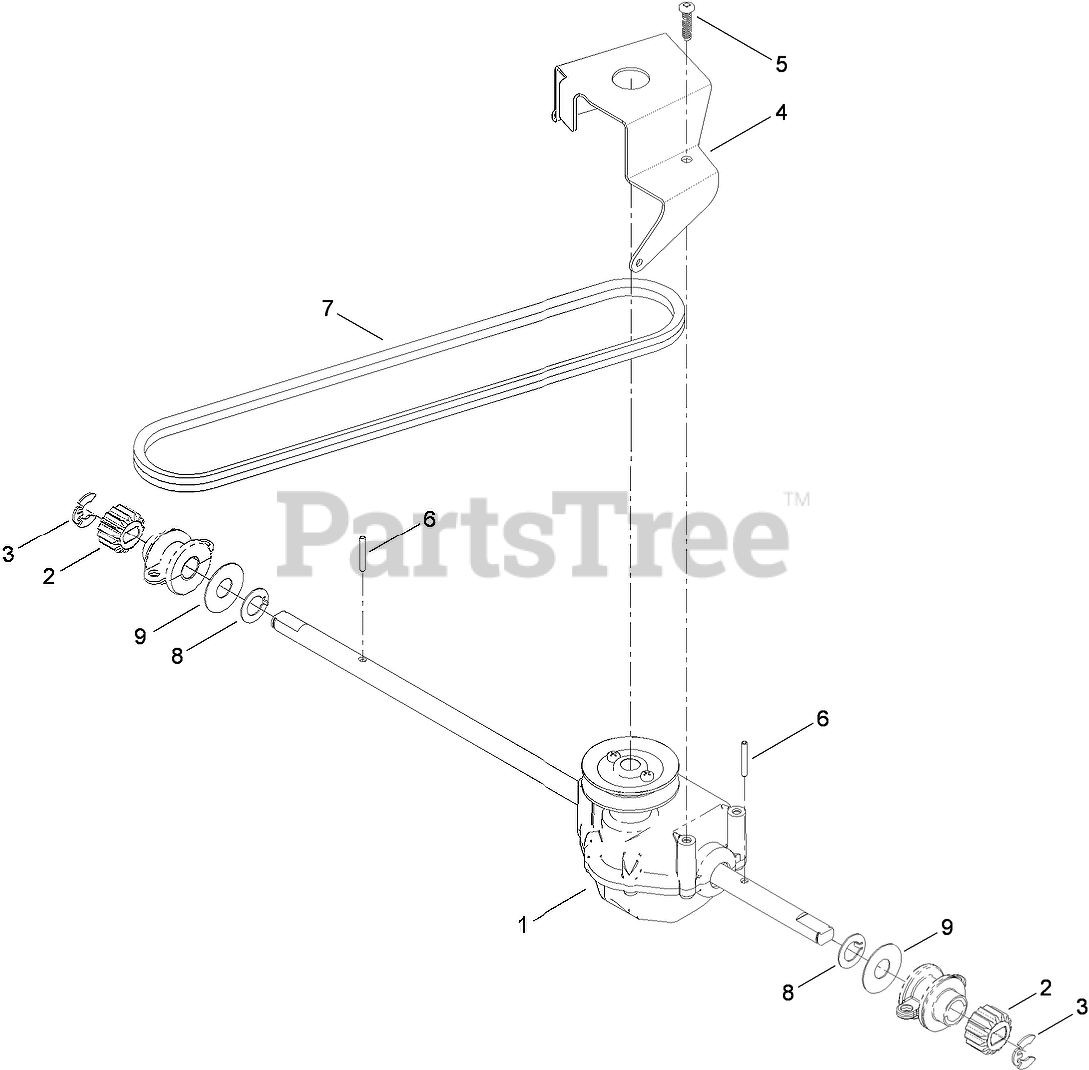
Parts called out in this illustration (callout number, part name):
1	TRANSMISSION-GEARBOX
2	GEAR-PINION, 15T
3	RING-CLIP, LOCKING
4	BRACKET-TRANSMISSION
5	SCREW-PLASTITE
6	PIN-ROLL
7	V-BELT
8	WASHER-THRUST, KEYED
9	WASHER-PLAIN
